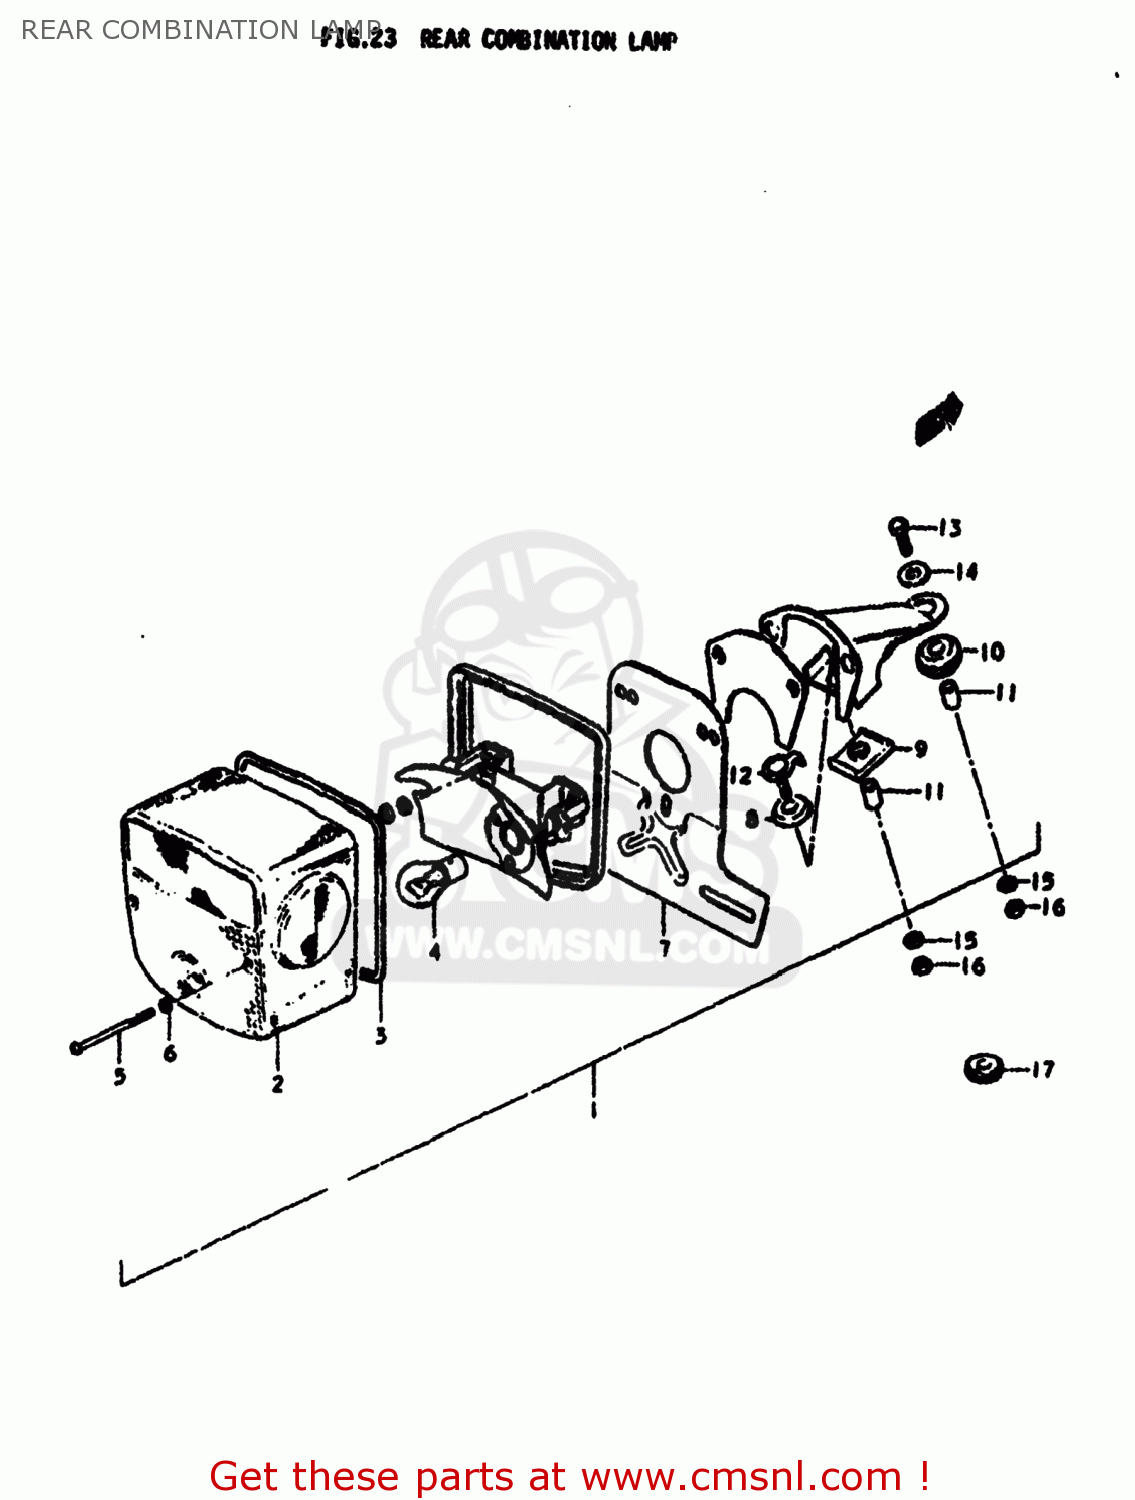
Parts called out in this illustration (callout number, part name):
1	LAMP ASSEMBLY,REAR COMBINATION
2	LENS,REAR COMBINATION LAMP
3	GASKET (NAS)
4	BULB(6V32/3CP,STANLEY)
5	SCREW (4X55)
6	GASKET (NAS)
7	BRACKET,LICENSE PLATE
8	CUSHION
9	CUSHION
10	CUSHION,REAR COMBINATION LAMP
11	SPACER,REAR COMBINATION LAMP
12	BOLT
13	BOLT
14	WASHER (6.5X20X1.2)
15	WASHER 6MM
16	NUT 6MM
17	GROMMET
